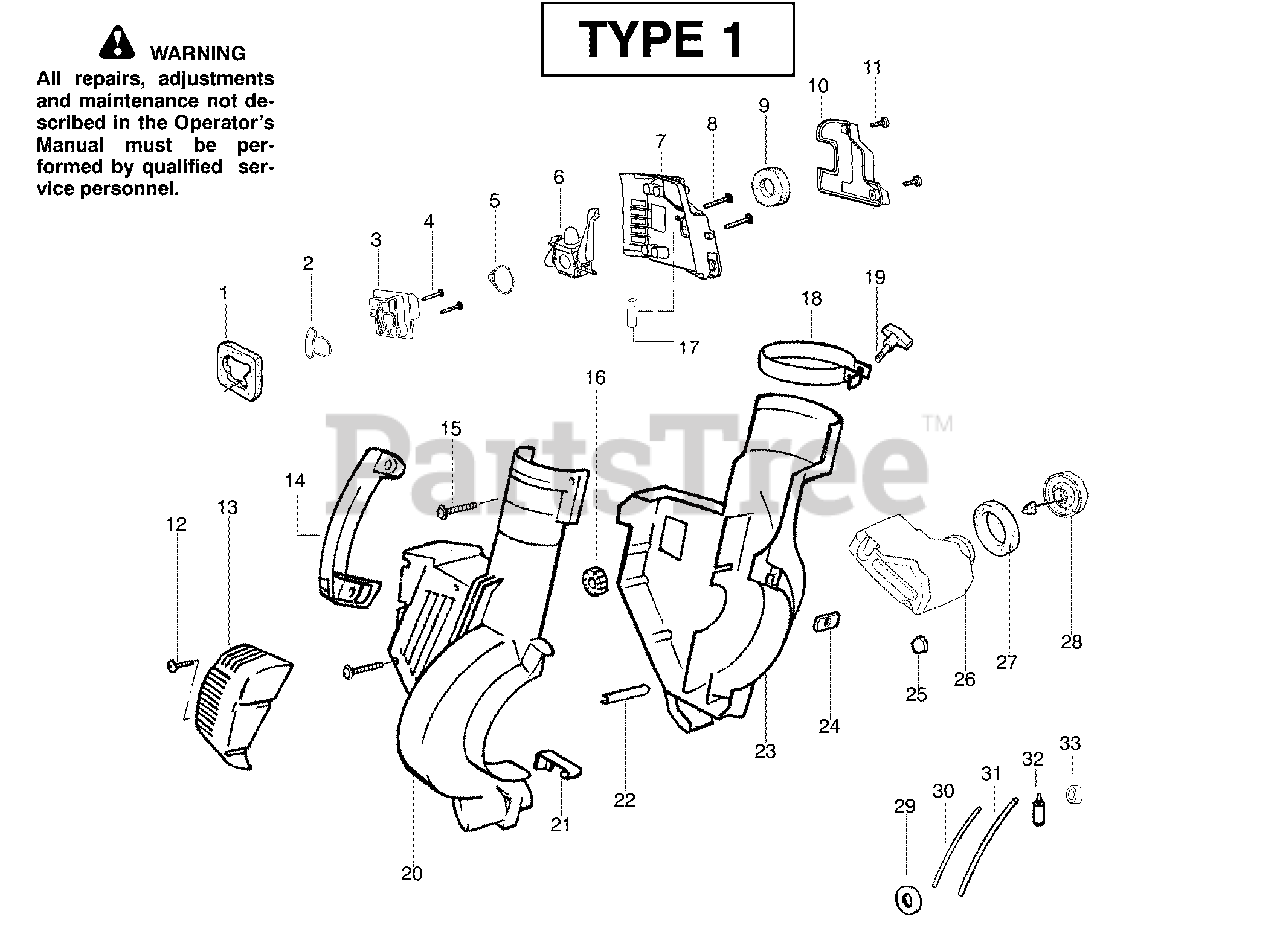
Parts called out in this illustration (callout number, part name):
1	Air Dam (Kit)
2	Gasket-Adapter (Kit)
3	Carburetor Adaptor
5	Gasket-Carburetor (Kit)
6	Kit-Carb Ass'y. (C1Q-W11)
8	Screw-Carb.
9	Filter-Air
10	Cover-Air Filter
11	Screw-Air Box Cover
13	Assy-Muffler Cover
16	Isolator
17	Foam-25.4mm (Kit)
18	Clamp-Blower Tube
19	Knob-Tube Clamp
20	Housing-Right (yellow)
21	Spring-Cover Latch
22	Guide-Starter Rope
23	Housing-Left (yellow)
25	Isolator-Crankcase
26	Assy-Fuel Tank
27	Gasket-Fuel Tank
28	Fuel Cap w/Retainer
29	Grommet-Shroud
30	Kit-Line Carb/Purge
31	Kit-Line Tank/Purge
32	Assy-Fuel Pick-up
33	Grommet-Fuel line (Kit)
